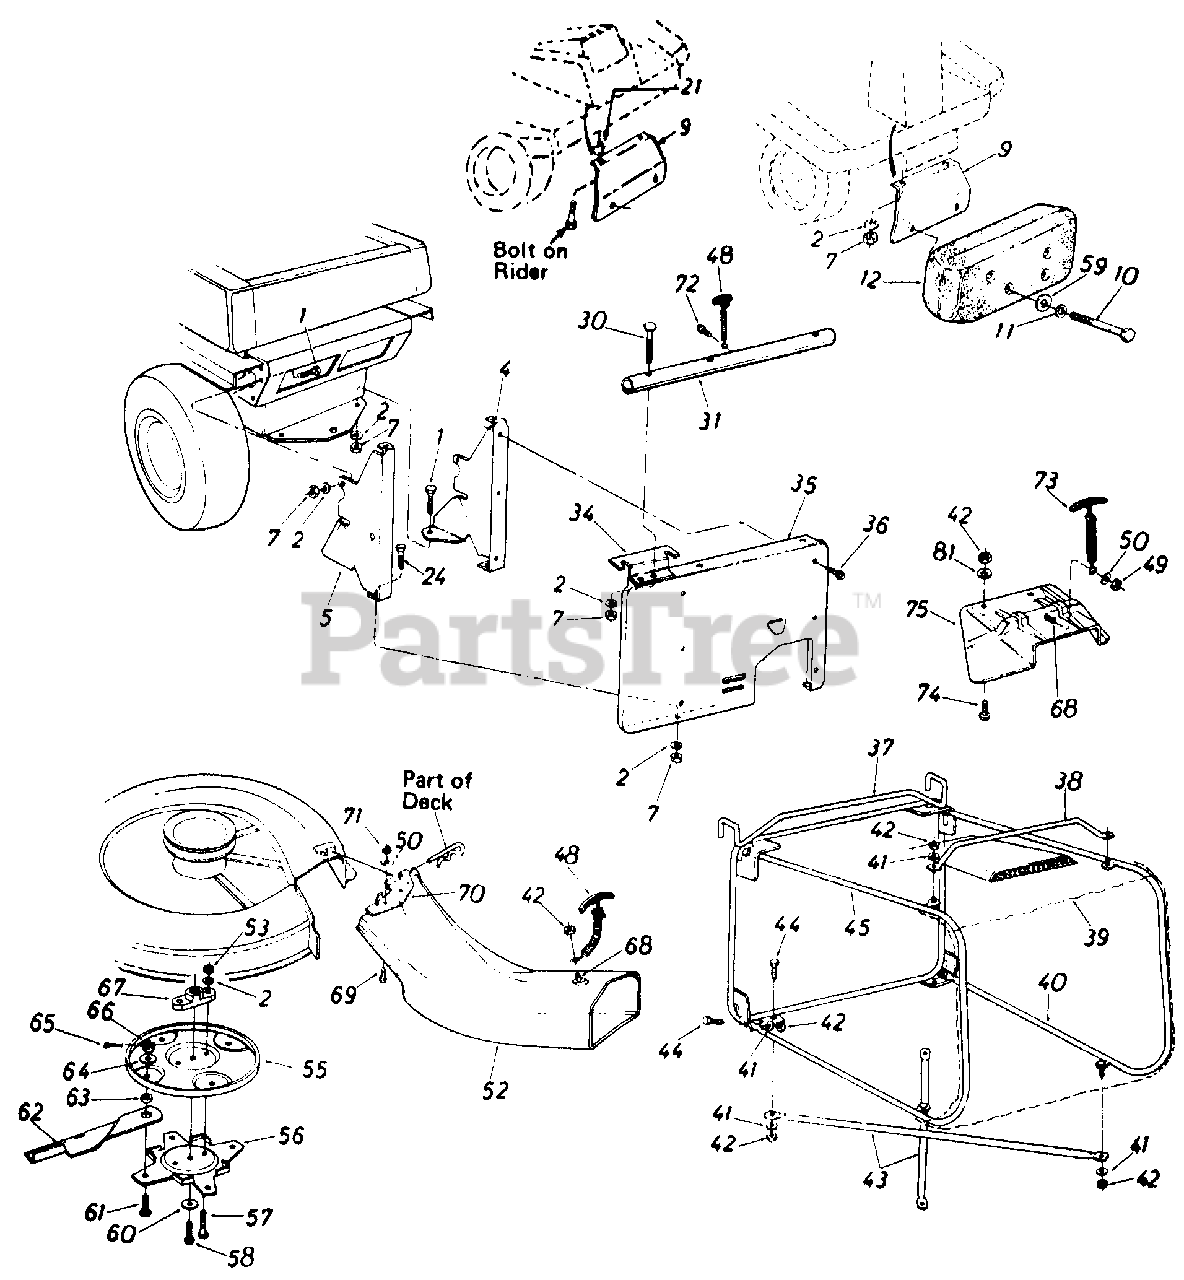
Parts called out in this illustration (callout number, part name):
1	Hex Bolt 5/16-18 X 1" Lg.
2	L-Wash. 5/16" I.D.
4	Catcher Support Brkt.-R.H.
5	Catcher Support Brkt.-L.H.
7	Hex Nut 5/16-18 Thd.
9	Counterweight Support Brkt. Ass'y.
10	Hex Bolt 3/8-16 x 4.5" Lg.
11	Bell-Wash. .40" I.D. x .88" O.D.
12	Counterweight 38 Ibs.
21	Spacer .380" I.D. x 1 O.D. x .32" Lg.
24	Hex Bolt 5/16-18 x 1.5" Lg.
30	Curved Carriage Bolt 5/16-18 x 1.75" Lg.
35	Rear Discharge Panel
36	HexWash. Hd. Self-TapScr. 1/4-20 x .5" Lg.
37	Grass Catcher Frame Ass'y.
42	Hex L-Nut 1/2-20 Thd.
43	Bottom Cross Brace
44	Hex Bolt 1/4-20 x .62" Lg.
50	L-Wash. 1/4" I.D.
52	R. D. Banana Chute Ass'y.
53	Hex Nut 5/16-24 Thd.
55	Upper Blade Disc
58	Hex Bolt 3/8-24 x 1.0 Lg.
59	Fl-Wash. .39 I.D. x 1.12 O.D.
60	Bell-Wash. .39H.D. x 1.38"
61	Shld. Bolt .50" Dia. x .36"
62	30" Blade Tip
63	Spacer .505" I.D. x .75' O.D. x 1.25H Lg.
64	Fl-Wash. .5" I.D. x 1.25" O.D.
65	Cotter Pin 8/32U Dia. x 1 Lg.
66	Hex Slotted Nut 1/2-20Thd.
67	Blade Adapter
68	Hex Bolt 1/4-20 x .5" Lg.
69	Truss Mach. Scr. 1/4-20 x .5" Lg.
72	Hex AB-Tap Scr. 1/4 x .62" Lg.
73	Hook Latch Ass'y.
74	Truss Mach. Scr. 1/4-20 x .50" Lg.
75	R. D. Chute Extension
81	Fl-Wash. .281" I.D. x .50 O.D. x .063
